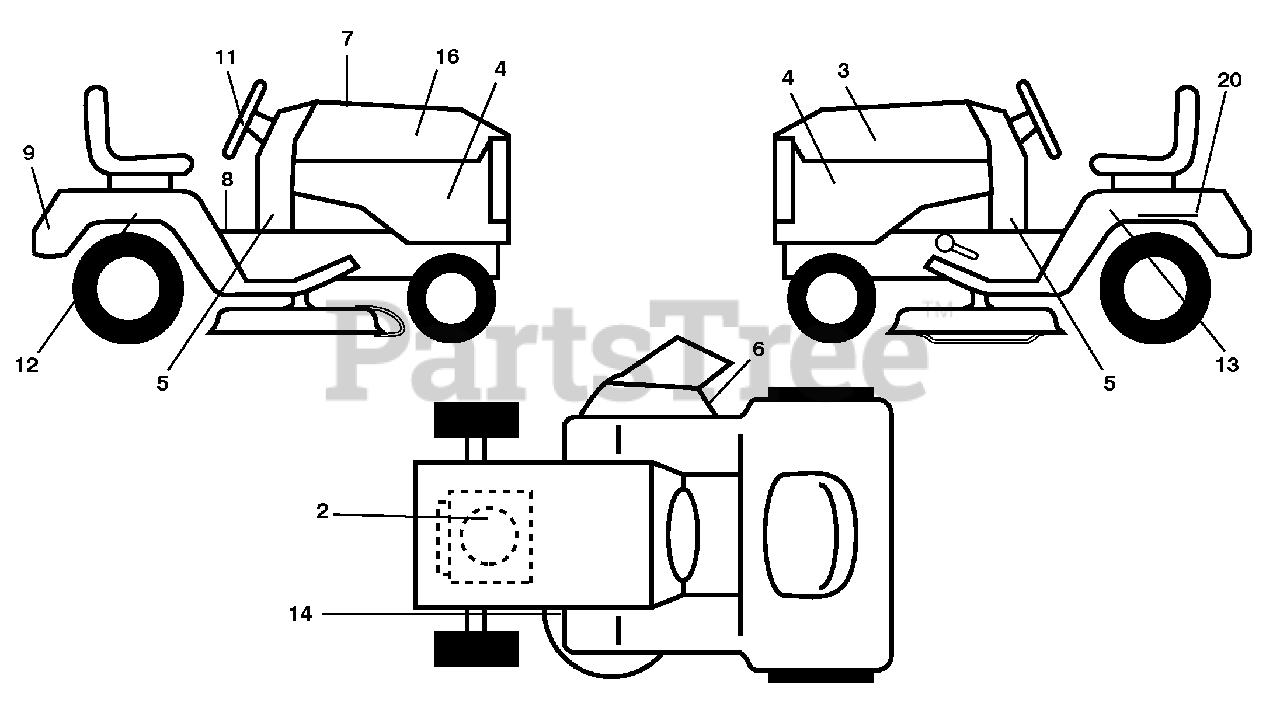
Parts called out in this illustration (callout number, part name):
2	Decal Eng. H.P.
3	Decal Hood LH
4	Decal Side Panel Logo
5	Decal Lwr Dash
6	Decal Warning, Keep Hand Away
7	Decal Replacement Parts
8	Decal Fender Warn S/F
9	Decal Fender Logo
11	Decal Ins Strg Whl
12	Decal Fend SD RH
13	Decal Fend SD LH
14	Decal V-Belt Schematic
16	Decal Hood RH
20	Decal Bat Dan/Psn
20	Pad Footrest LH
20	Pad Footrest RH
20	Manual Operator's (Eng/French)
20	Manual Parts (Eng/French)
